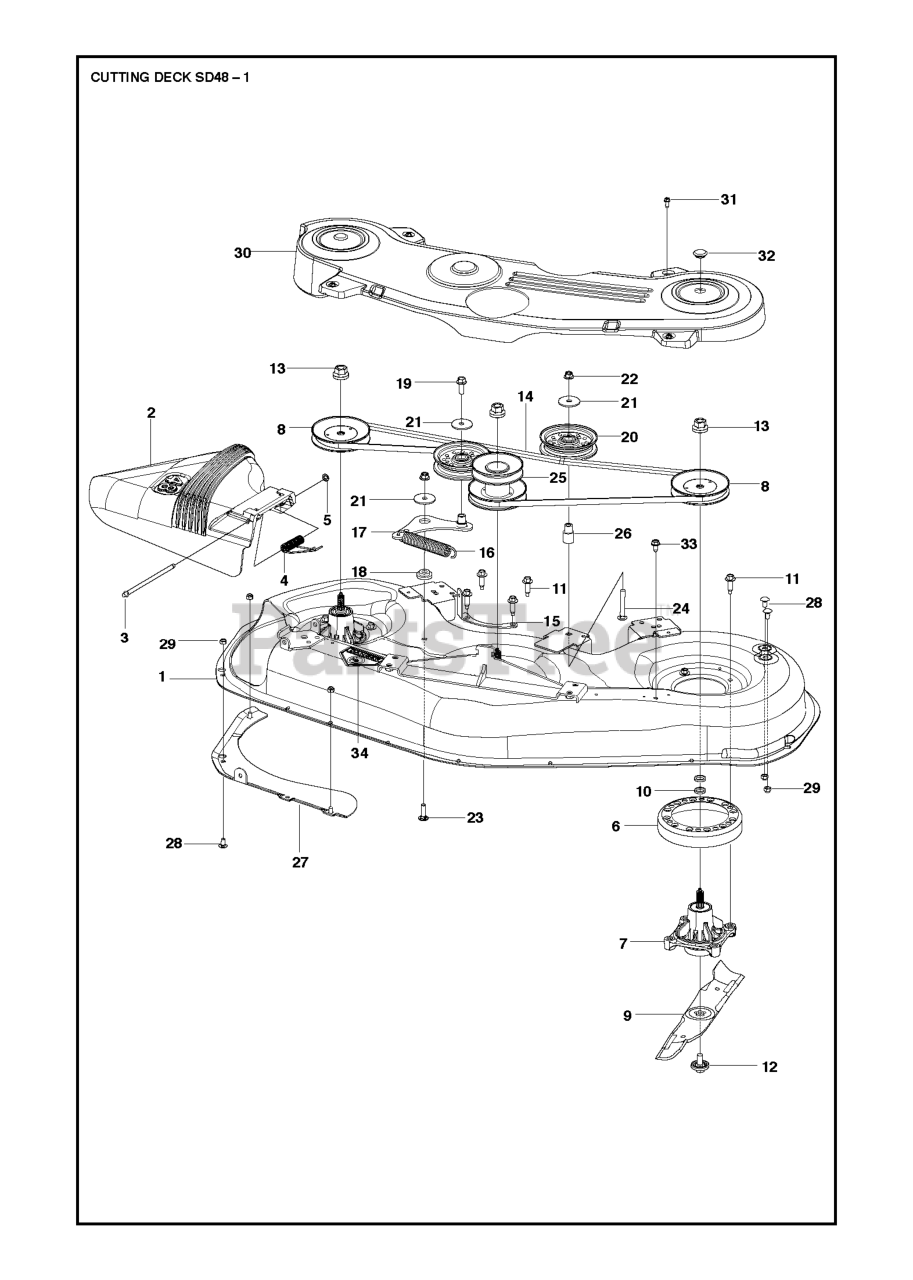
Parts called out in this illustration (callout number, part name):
2	DEFLECTOR.ASM.BLACK.48"
3	ROD.HINGE
4	SPRING, TORSION
5	NUT PUSH M
6	STRIPPER.MANDREL.ROUND.BLACK
7	MANDREL ASM
8	MANDREL.PULLEY.38.BRIGHT.ZINC
9	48" HI-LIFT BLADE
10	WASHER.SPACER.MANDREL
11	SCREW, WASHER HEAD
12	BOLT.WASHER.ASM.7/16-2
13	NUT.FLANGE.LOCK.TOP
14	V-BELT.MOWER.
16	SPRING.TENSION
18	BUSHING.FLANGE..405
19	HHFS 3/8-16 X 1 GRD 5 ZD
20	IDLER PULLEY
21	WASHER, 3/8 SPEC
22	NUT 3/8-16 HEX FLG NYLOC ZD
23	Carriage Bolt 3/8-16 x 1-1/4
24	Bolt, Carriage 3/8-16 x 2-1/2
25	RP PULLEY.ASSY.STACKED
26	BUSHING.FLANGE
27	BAFFLE, VORTEX MWR
28	Bolt, Carriage 5/16-18 x 5/8
29	Nut, Hex, with Lockwasher Insert 5/16-18
30	SHIELD.BELT.48".STAMPED
31	SCREW.1/4-20X5/8
32	PLUG.HOLE.MANDREL.COVER
33	Screw Hexwsh Thdrol 3/8-16 x 3/4
34	DECAL, CPSC
